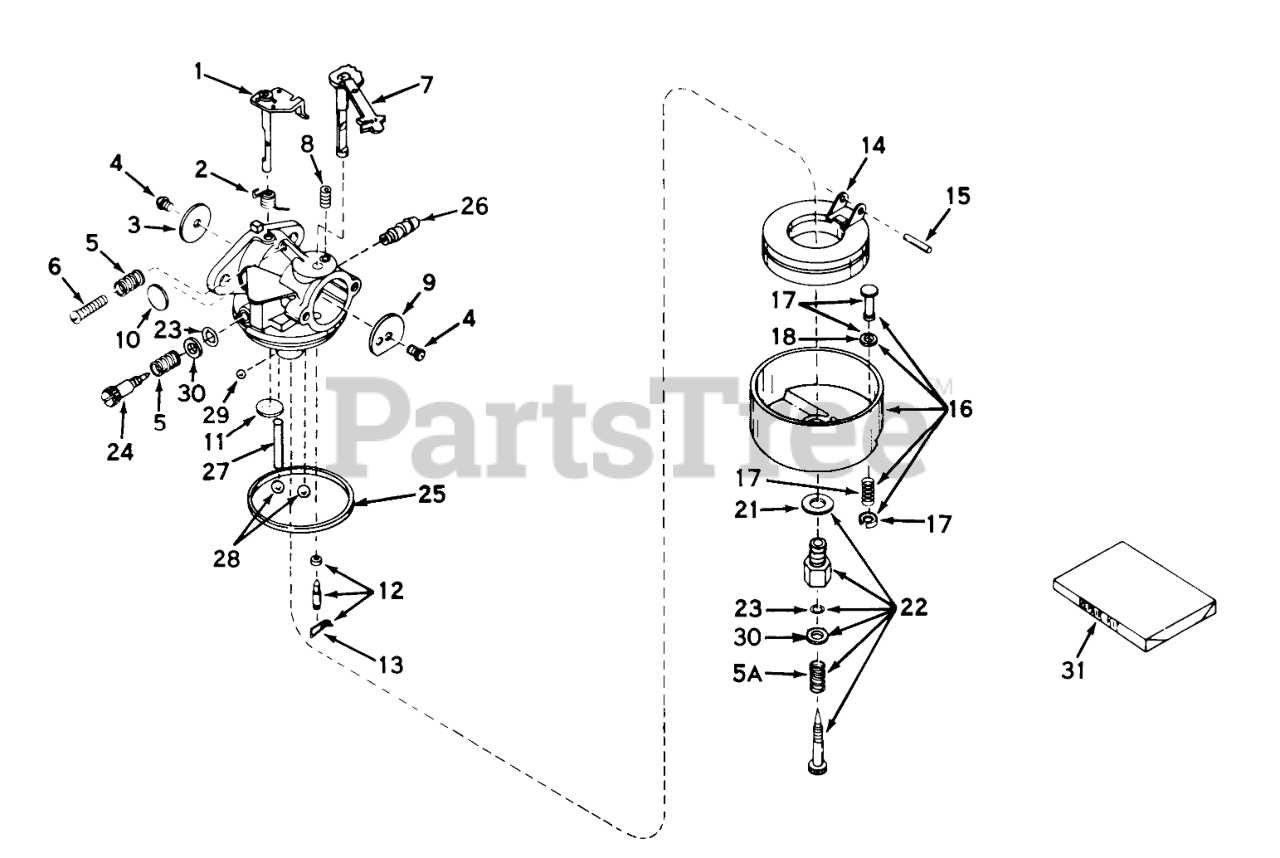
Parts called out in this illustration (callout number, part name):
1	Shaft/Lever-Throttle
2	Spring, Return
3	Shutter-Throttle
4	Screw-Shutter
5	Spring-Tension
6	Screw-Throttle Crack Screw / Idle Speed
7	Shaft & Lever Ass-y Choke
8	Spring-Positioning, Choke
9	Shutter-Choke
10	Plug-Welch, Idle Mixture Well
11	Plug-Welch, Atmospheric Vent
12	Inlet Needle, Seat & Clip Ass-y (Incl. No. 13)
13	Clip-Spring
14	Float,Carburetor
15	Shaft-Float
16	Bowl & Drain Ass-y, Float (Incl. No. 17)
17	Plunger Ass-y, Drain (Incl. No. 18)
18	Gasket-Plunger, Drain
21	Washer-Bowl Nut
22	Adjustment Screw Ass-y, Main (Incl.Nos. 5A, 21, 23 & 30)
23	"O"Ring
24	Screw, Idle Adj.
25	O Ring-Bowl, Float
26	Fitting, Fuel inlet
28	Plug, Cup
29	BalI, Steel
31	Kit-Repair
